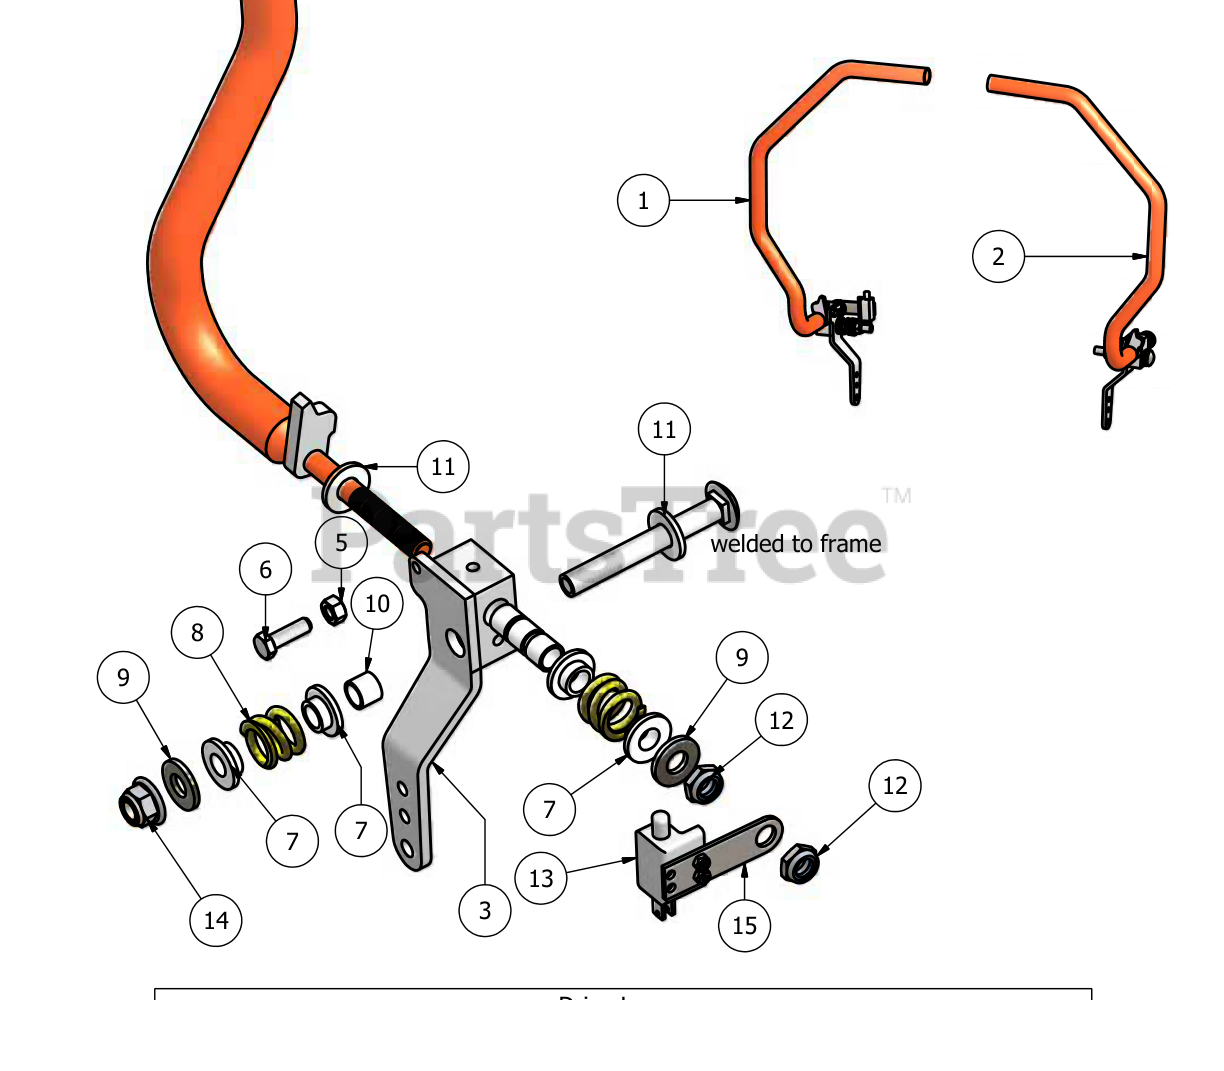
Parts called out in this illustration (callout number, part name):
1	Right Drive Lever
2	Left Drive Lever
3	Drive Arm Lever Housing - Right
4	Drive Arm Lever Housing - Left
6	5/16" x 3/4" Bolt
7	Nylon Washer .515 ID Shoulder
9	7/16 Flat Washer
10	Nylon Bushing .507 ID
11	.505 Nylon Washer
12	1/2" Nylock Nut (1/2 Jam)
13	Electric Saftey Switch
14	1/2" Flange Lock Nut
15	Switch Bracket
